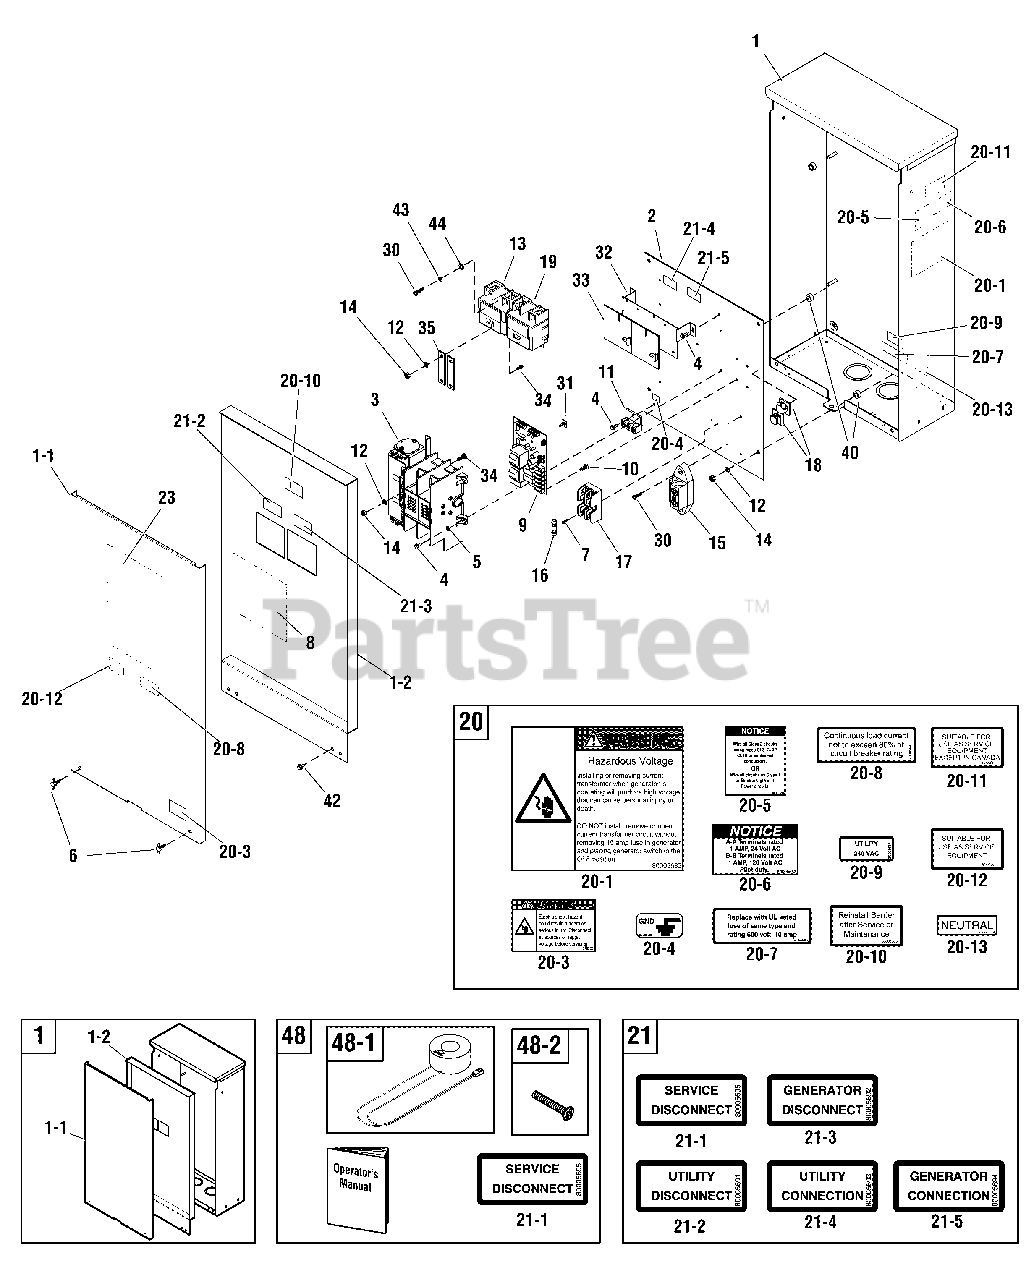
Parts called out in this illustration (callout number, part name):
1	ENCLOSURE
2	BACK PANEL
3	SWITCH, Transfer
4	* SCREW, Hex Head, Trilobular, #10-32 x 1/2
5	* WASHER, Ext. Tooth, #10
6	SCREW
7	* SCREW, Hex Head, Trilobular, #6- 32 x 3/8
8	INSULATION, Dead Front
9	CONTROL, Board
10	SPACER, PCB Board, 1/2
11	LUG
12	* WASHER, Lock 1/4
13	BREAKER, Circuit, 200A
14	* NUT, 1/4-20
15	TERMINAL, Neutral
18	CLIP, Latching Wire
19	BREAKER, Circuit, 200A
20	DECAL SHEET-WARNINGS
20-1	DECAL, CT Warning
20-3	DECAL, Warning Shock
20-4	DECAL, Ground
20-5	DECAL, Wire Circuits
20-6	DECAL, Contacts Rating
20-7	DECAL, Fuse
20-8	DECAL, Suit. as Service Equip.
20-9	DECAL, Sensing, Utility
20-10	DECAL, Reinstall Barrier
20-11	DECAL, Not Suitable
20-12	DECAL, Breaker, Circuit
20-13	DECAL
21	DECAL SHEET-CONNECTIONS
21-1	DECAL, Service Disconnect
21-2	DECAL, Disconnect Utility
21-3	DECAL, Gen Disconnect
21-4	DECAL, Connection, Utility
21-5	DECAL, Connect Gen
23	DECAL, 200A, ATS
30	* SCREW, Hex Head, Trilobular, #10-32 x 3/4
32	BRACKET, Circuit Breaker Mounting
33	INSULATOR, Circuit Breaker
34	* SCREW, Phillips Head, 1/4-20 x 3/4
40	SPACER
42	* SCREW, Hex Head, Trilobular, #8-32 x 3/8
43	* WASHER, Lock, #10
44	* WASHER, Flat, #10
48	KIT-MANUAL ACC
48-1	CURRENT TRANSFORMER
